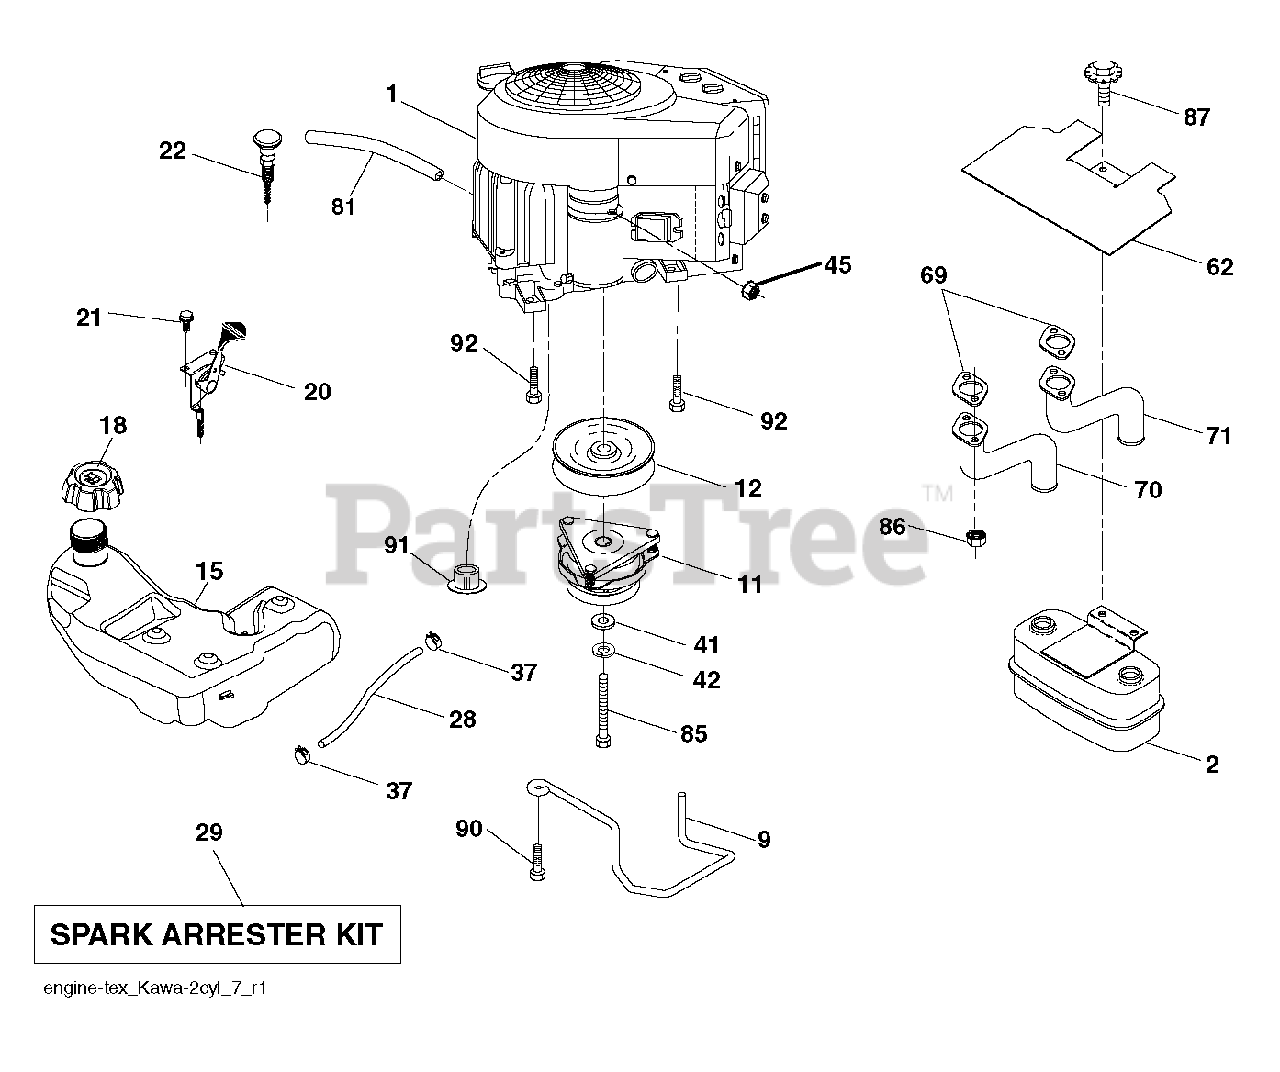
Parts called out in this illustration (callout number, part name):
2	MUFFLER.ASM.TWN.EXTNDED.DFLCTR
9	KEEPER.BELT.ENGINE.4.2
11	CLUTCH MZ ZTR GT.48/54"1.125"
12	PULLEY ENGINE
15	TANK.ASM.4.GAL.EPA.ONE.PORT
18	CAP.ASM.FL.RITCH.3"E10.SYM.498
20	CONTROL.THROTTLE.COBRA.BLACK
21	SCREW.#10 X 0.750.BOS
22	CONTROL, CHOKE
28	LINE.FUEL.64"REAR.EMIS
29	KIT.SPARK ARRESTOR 794945 B&S
37	HOSE CLAMP
42	LOCKWASHER
45	NUT
62	SHIELD.HEAT.MUFFLER
70	TUBE.EXHAUST.RH.FR961/FR730
71	TUBE.EXHAUST.RH.FR961/FR730
81	TUBE, DRAIN OIL ASM.
85	BOLT HEX 7/16-20 X 3.75 GR. 5
86	NUT.HEX.FLANGE.TOPLOCK
87	BOLT, 5/16-18 X 1 3/4
90	SCREW 3/8-16X1
91	BUSHING.1.375OD
92	SCREW 3/8-16X1
